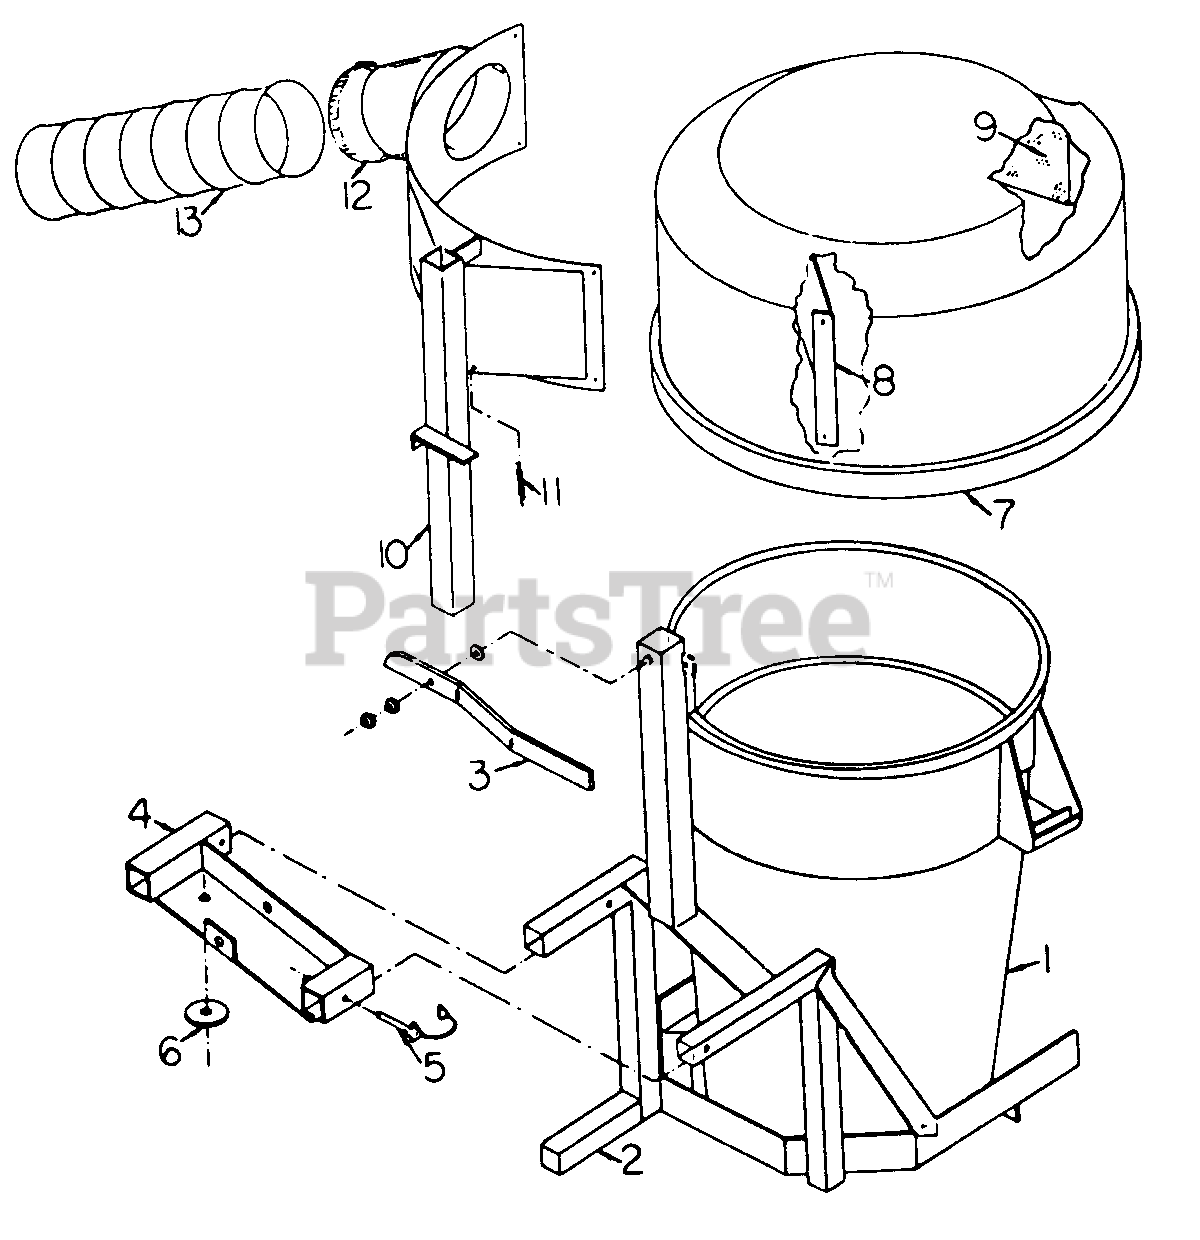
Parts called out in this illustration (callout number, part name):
3	Handle
4	Barrel Mountlng Bracket
6	Body Mount Washer
10	Barrel Lid Mount
13	Hose
